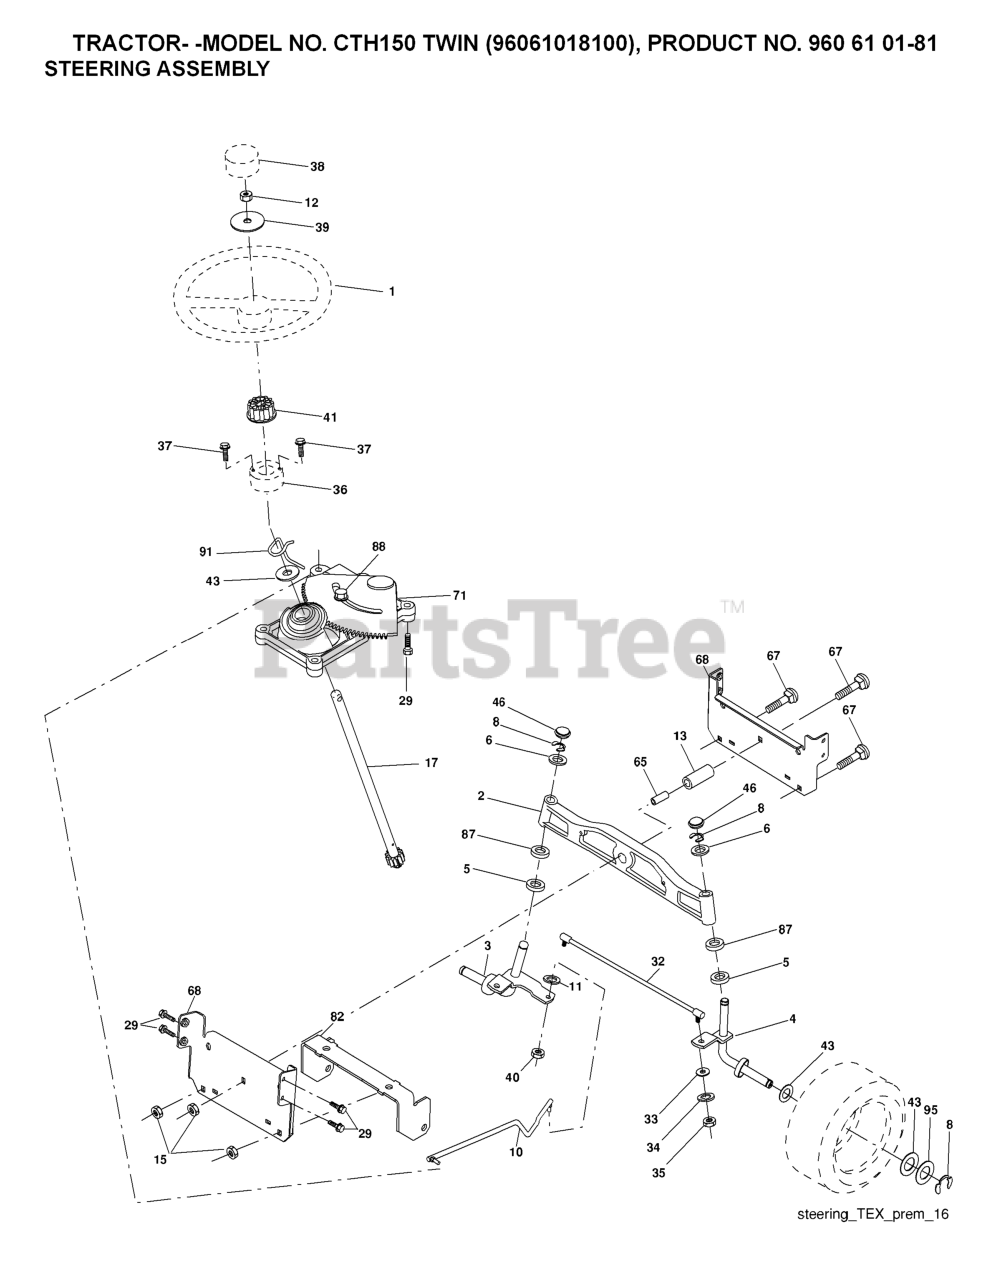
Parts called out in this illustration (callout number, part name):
1	STEERING WHEEL
2	AXLE ASSY FRONT
3	SPINDLE.ASM.LH.15"TIRES
4	SPINDLE.ASM.RH.15"TIRES
5	THRUST WASHER
10	DRAGLINK.15".TIRES.2001
11	WASHER, LOCK 3/8
12	NUT.HEX.1/2-20
13	TUBE, PIVOT AXLE
15	NUT
17	SHAFT ASM STRG
29	SCREW, 3/8-16X3/4
32	TIE ROD
33	WASHER M
34	WASHER.LOCK.HVY.HLCL.SPR.5/16
35	NUT, CROWNLOCK
36	BUSHING, STRG. BLK
37	SCREW.TT.#10-32X.5.3/8.FLANGE
38	INSERT.CAP.STRG.WH.GRAY
39	WASHER 9/16"ID, 2 3/8"OD
40	NUT CROWNLOCK 3/8-24
41	ADAPTER, WHEEL STNG..
46	CAP.SPINDLE.BLACK
65	SPACER BRACE AXLE
67	BOLT CARRIAGE
68	BRACE.AXLE.15"TIRES
71	STEERING ASM
82	BRACKET.SUSP.CHASSIS.FRONT.15
87	WASHER, FLAT .781 X 1 1/2"
88	BOLT, SHOULDER 7/16-20
91	CLIP.STEERING
95	WASHER.HARDENED
